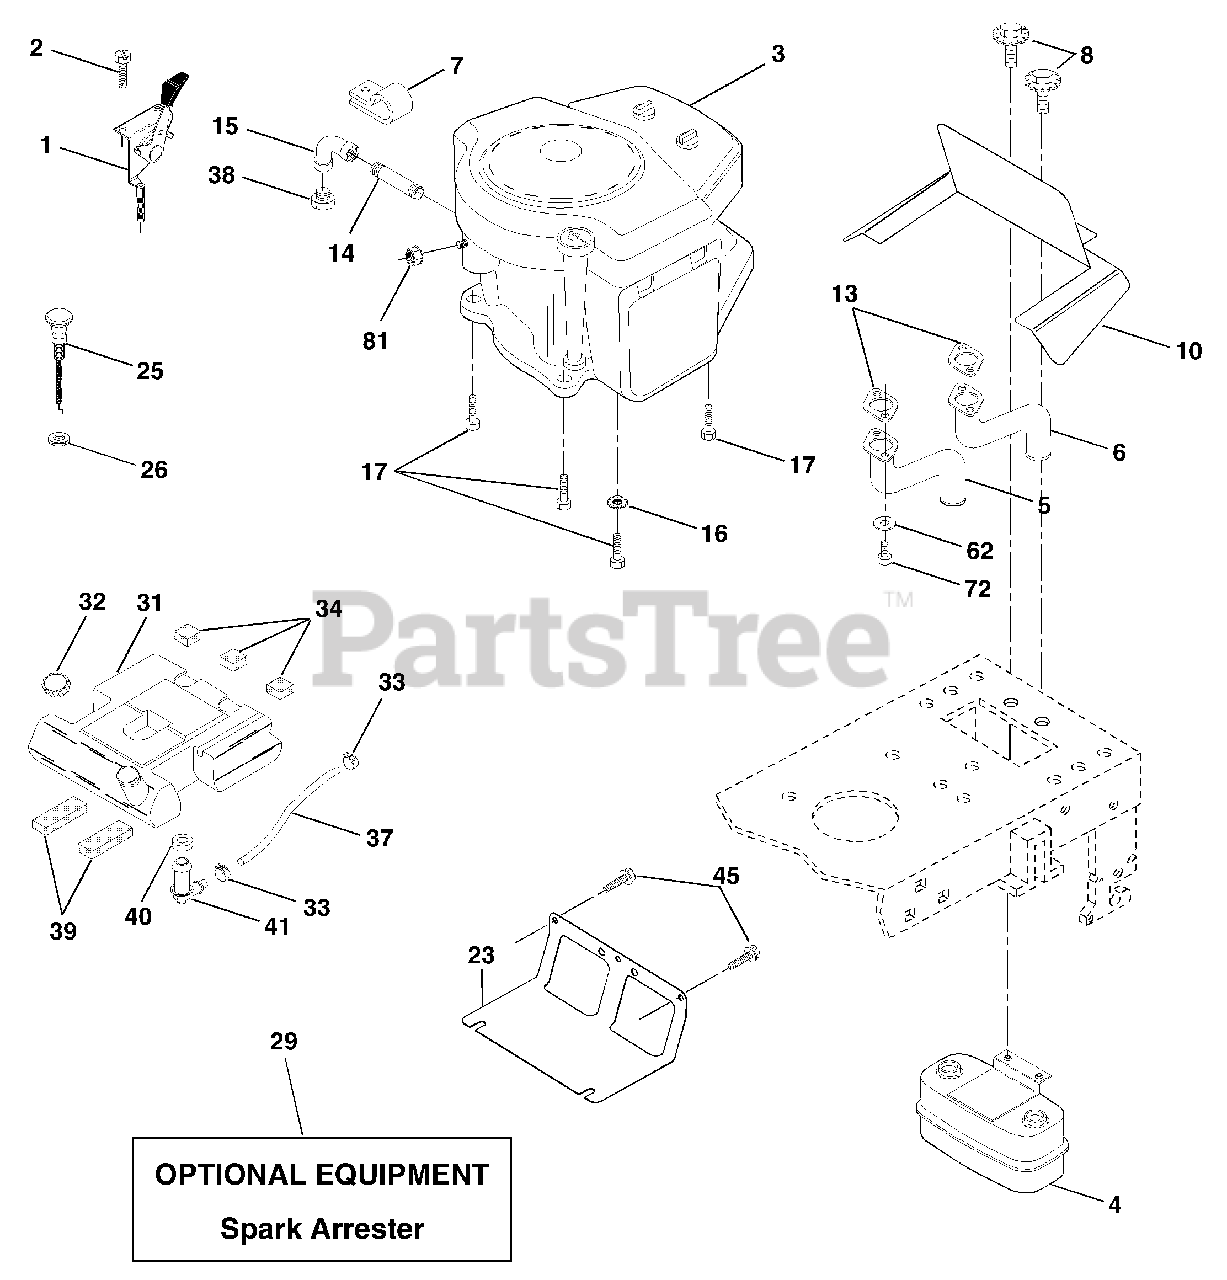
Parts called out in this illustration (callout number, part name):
1	Control, Throttle
2	Screw, Hex Head, Thread Cutting 1/4-20 x 5/8
4	Muffler
5	Tube, Manifold, LH
6	Tube, Manifold, RH
7	Clip Insulated
8	Bolt 5/16-18 UNC x 3/4 w/Sems
10	Shield, Browning
13	Muffler Gasket
14	Nipple, Pipe 3/8 NPT x 4-1/2
15	Elbow, Standard 90° 3/8-18 NPT
16	Washer, Lock, External Tooth 3/8
17	Screw Thdrol 3/8-16 x 1-1/2
23	Shield, Browning / Debris Guard
25	Choke Control
26	Nut, Keps 3/8-24 UNF
29	Kit, Spark Arrestor
31	Tank Fuel 3 50 Rear
32	Cap Asm Fuel W/sym Vented
33	Clamp, Hose
34	Pad, Spacer
37	Line, Fuel
38	Plug, Oil Drain
39	Pad, Idler
40	Bushing
41	Stem, Fuel Tank
45	Screw Hex wsh Thdrol 3/8-16 x 3/4
62	Washer Lock 5/16
72	Screw Hex Hd Cap 5/16-18 x 3/4
81	Nut Keps Hex 1/4-20 Unc
